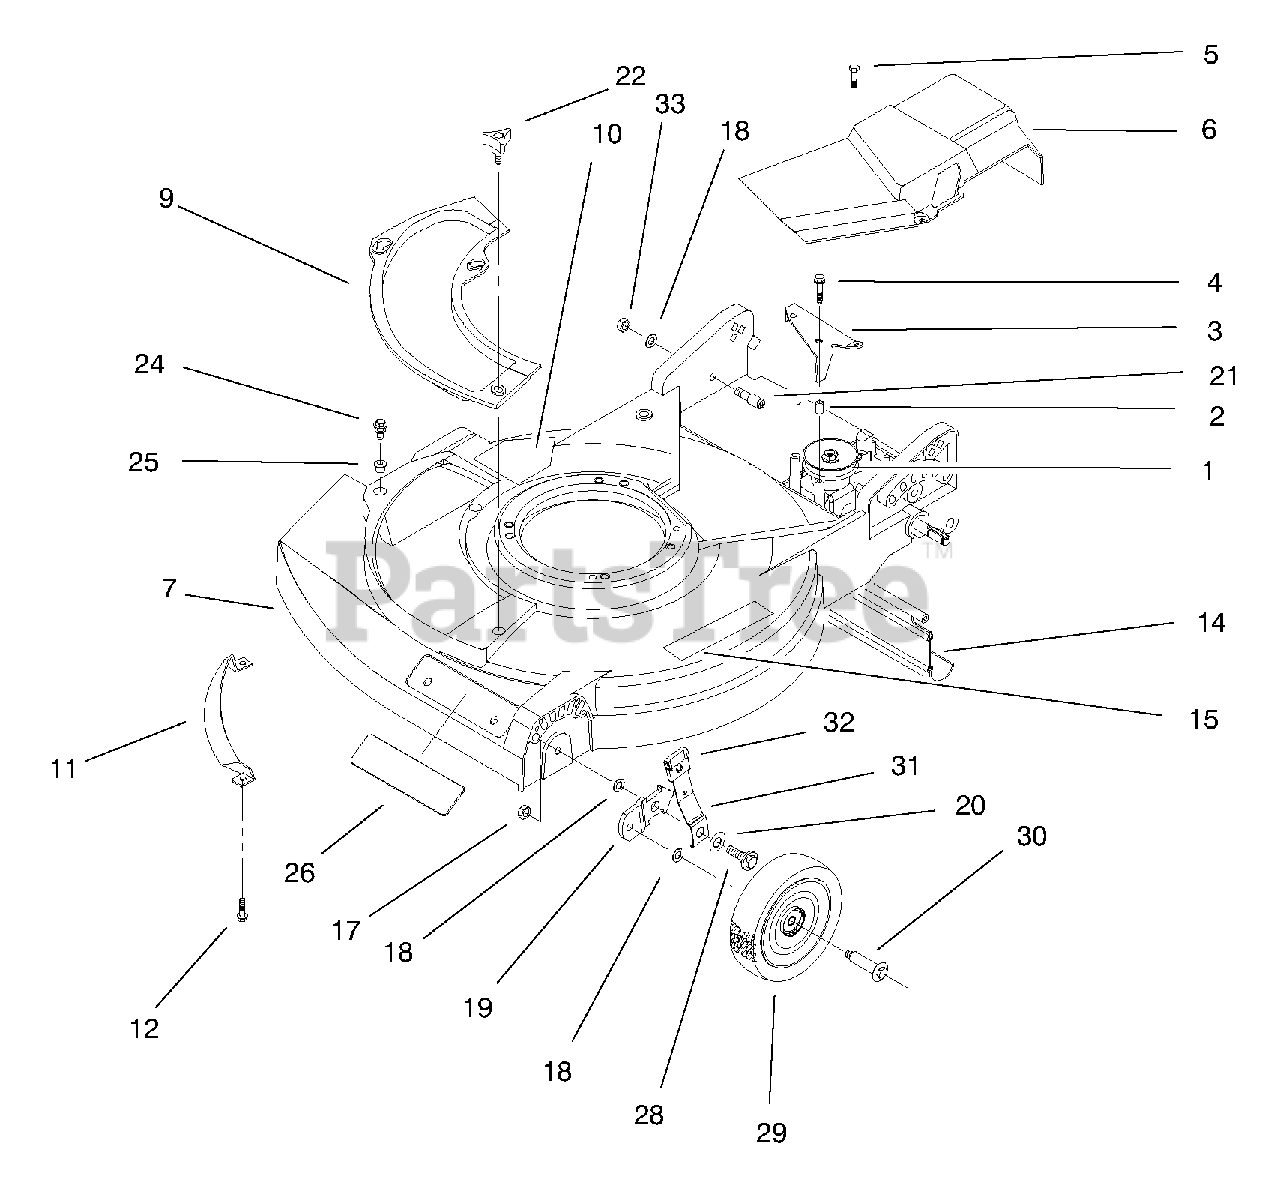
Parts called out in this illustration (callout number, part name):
1	Gear Case Assembly
2	Bushing-Spacer
3	Bracket-Actuator
4	Screw
5	Screw-Thr'd Form
6	Cover-Drive
7	Housing (Incl. Ref. #10 & 15)
9	Plate-Cover
10	Decal-Danger
11	Toe Bar
12	Screw-Hex Washer Hd.
14	Shield-Trailing
15	Decal-Warning
17	Nut-Lock
19	Bracket-Wheel Height Adj.
20	Washer-Belleville
21	Bolt-Shoulder
22	Knob-Cover Plate
24	Screw-Sems Thr'd Form
26	Decal-Deck
28	Bolt-Shoulder
29	Wheel & Tire Assembly-6"
30	Bolt-Wheel
31	Spring Arm Ass'y-Front
32	Knob-Height Adjust
33	Nut-Lock
